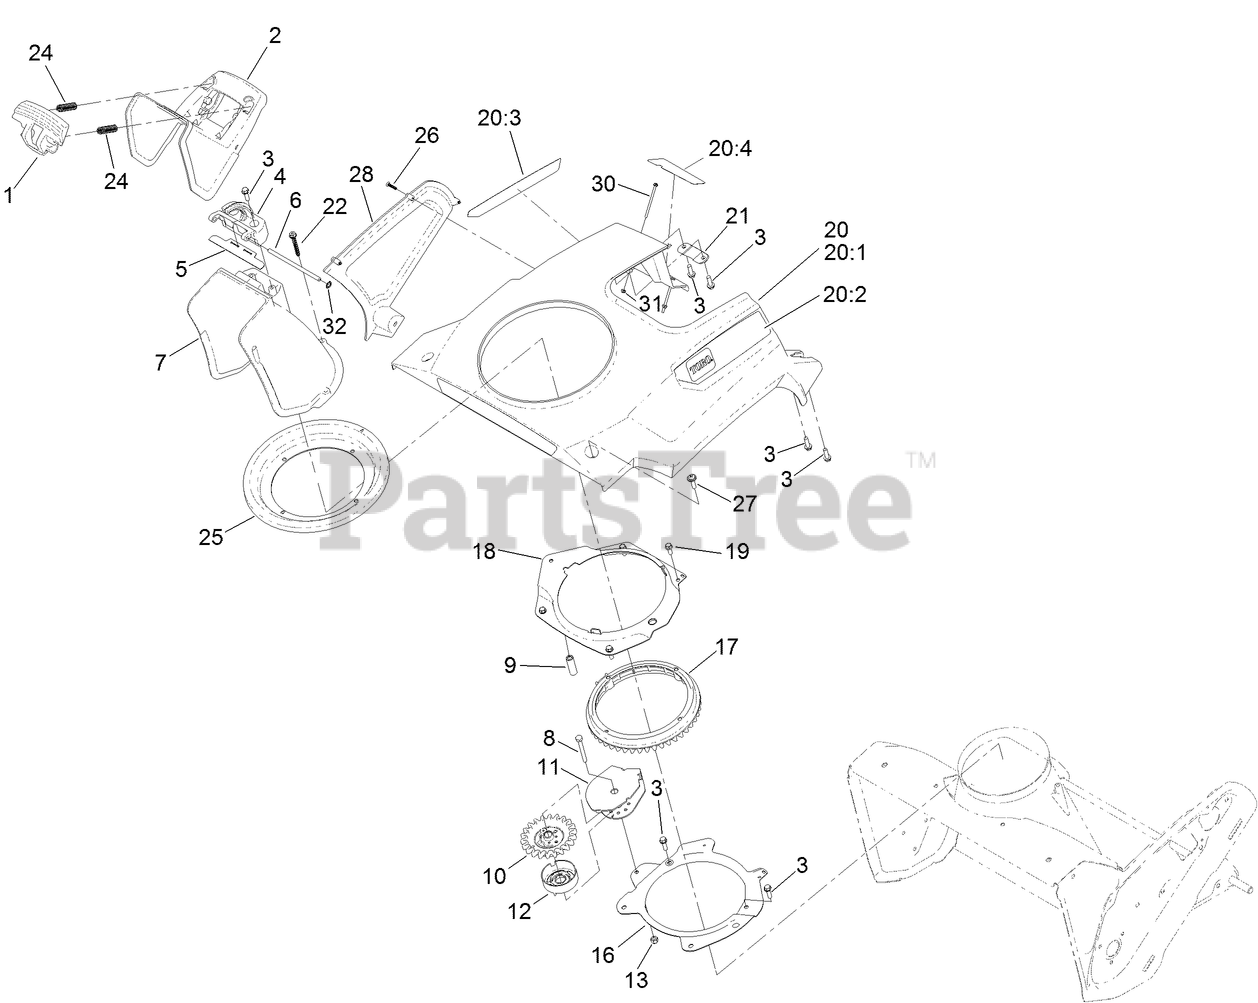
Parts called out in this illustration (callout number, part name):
1	TRIGGER-DEFLECTOR
2	DEFLECTOR-CHUTE, CE
3	SCREW-HWH
4	HINGE-RATCHET, DEFLECTOR
5	SEAL-DEFLECTOR
6	HINGE PIN-DEFLECTOR
8	SCREW-HH
9	SPACER-SLEEVE, PINION
10	PINION-GEAR
11	BRACKET-PINION
12	RETAINER-CABLE
13	NUT-LOCK, NI
16	RING-SUPPORT, CHUTE
17	RING-CHUTE, GEAR
18	RETAINER-RING, CHUTE
19	SCREW-HWH
20	SHROUD ASM, W/DECALS
20:1	SHROUD ASM, W/ARTWORK
20:2	DECAL-SHROUD LH
20:3	DECAL-SHROUD RH
20:4	DECAL-ENGINE, ELECTRIC START
21	RETAINER-SHROUD
22	SCREW-PLASTITE
24	SPRING-COMPRESSION
25	SEAL-RING, CHUTE
26	SCREW-PPH
27	SCREW-PPH
28	COVER-SIDE
30	SCREW-HWH
31	NUT-HEX
32	RING-RETAINING
